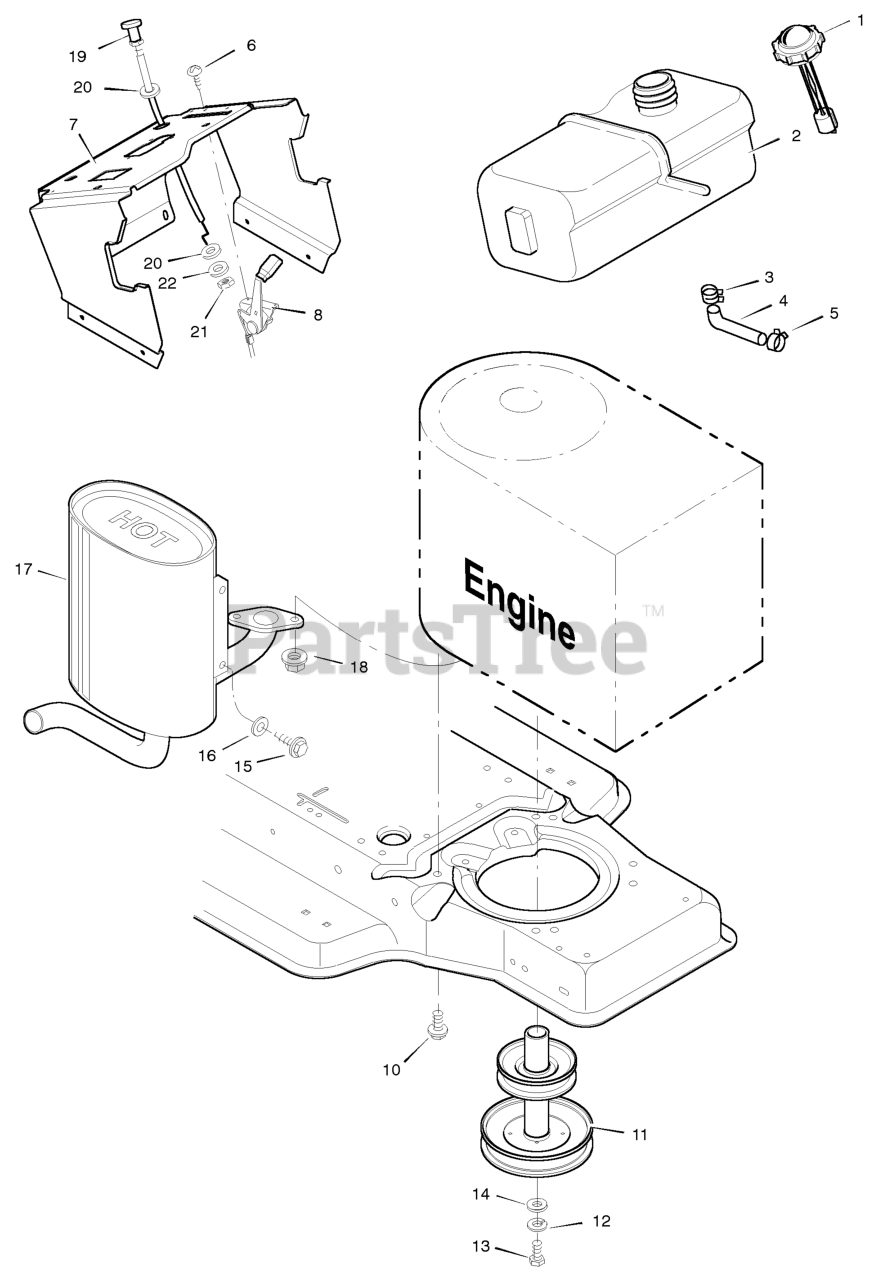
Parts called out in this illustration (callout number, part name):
1	Fuel Cap
2	Fuel Tank
3	Hose Clamp
4	Fuel Line
5	Hose Clamp
7	Support, Dash
8	Throttle Control
9	Engine *
10	Bolt, Engine Mount
11	Stack Pulley Assembly
12	Lockwasher
13	Bolt, Hex
17	Muffler
18	Nut, Hex
19	Cable, Choke
20	Washer
21	Nut, Hex
22	Washer
